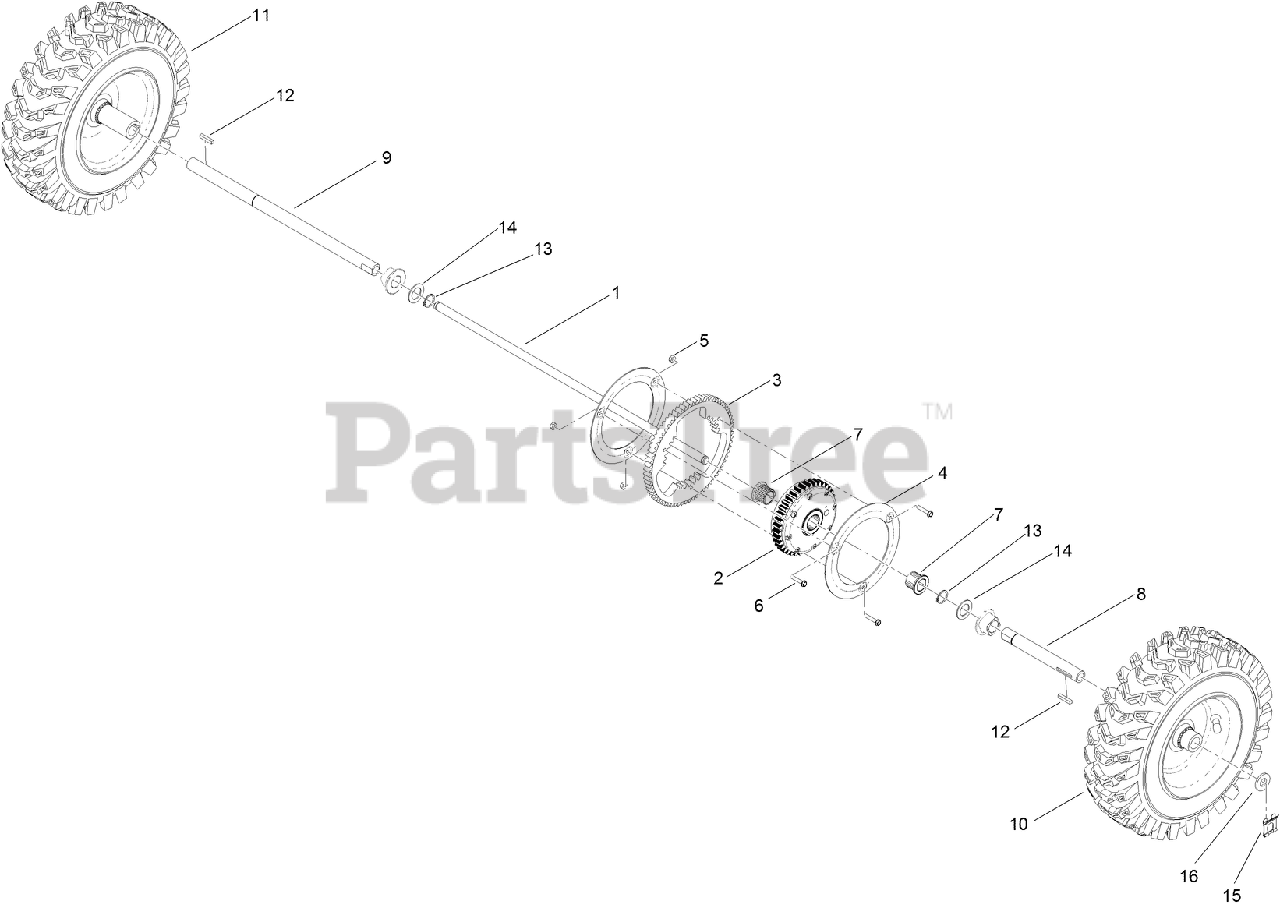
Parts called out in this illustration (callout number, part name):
2	TRANSMISSION
3	GEAR-AXLE
4	PLATE-GEAR
5	NUT-LOCK, NI
6	SCREW-HWH
7	GEAR-TUBE, AXLE
8	TUBE-AXLE
9	TUBE-AXLE
10	LH WHEEL AND TIRE ASM
11	RH WHEEL AND TIRE ASM
12	KEY-SQUARE
13	RING-SNAP
14	WASHER-THRUST
15	CLIP-PIN
16	WASHER-THRUST, PLAIN
